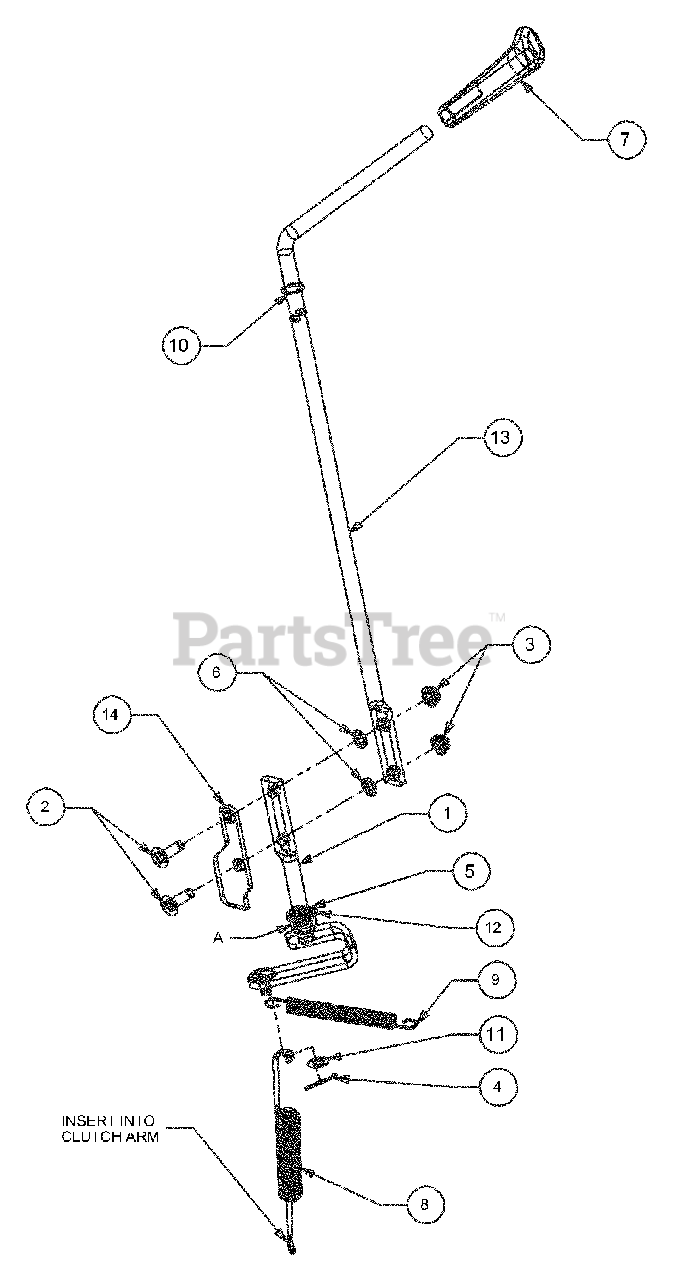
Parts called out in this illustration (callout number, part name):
1	LVR ASM:ENGAGE 500
2	SCR:CARR:SPL:5/16-18:1.00
3	NUT:FLGLK:5/16-18:GR5:SD LK
4	PIN:COT:3/32:1.0
5	E-RING FOR .500 DIA SHAFT
6	NUT:SPD:.3125 ID
7	KNOB:PTO
8	SPR:EXTN:.75 OD X 10.6 LG
9	SPR:EXTN:.50 DIA X 5.0 LG
10	WASH:FLAT:.510 X .750 X .033
11	WASH:THRST:.375x.70x.030
12	BRG:FLG:HEX SPLIT .500 ID
14	BRKT:ENGAG:STOP
